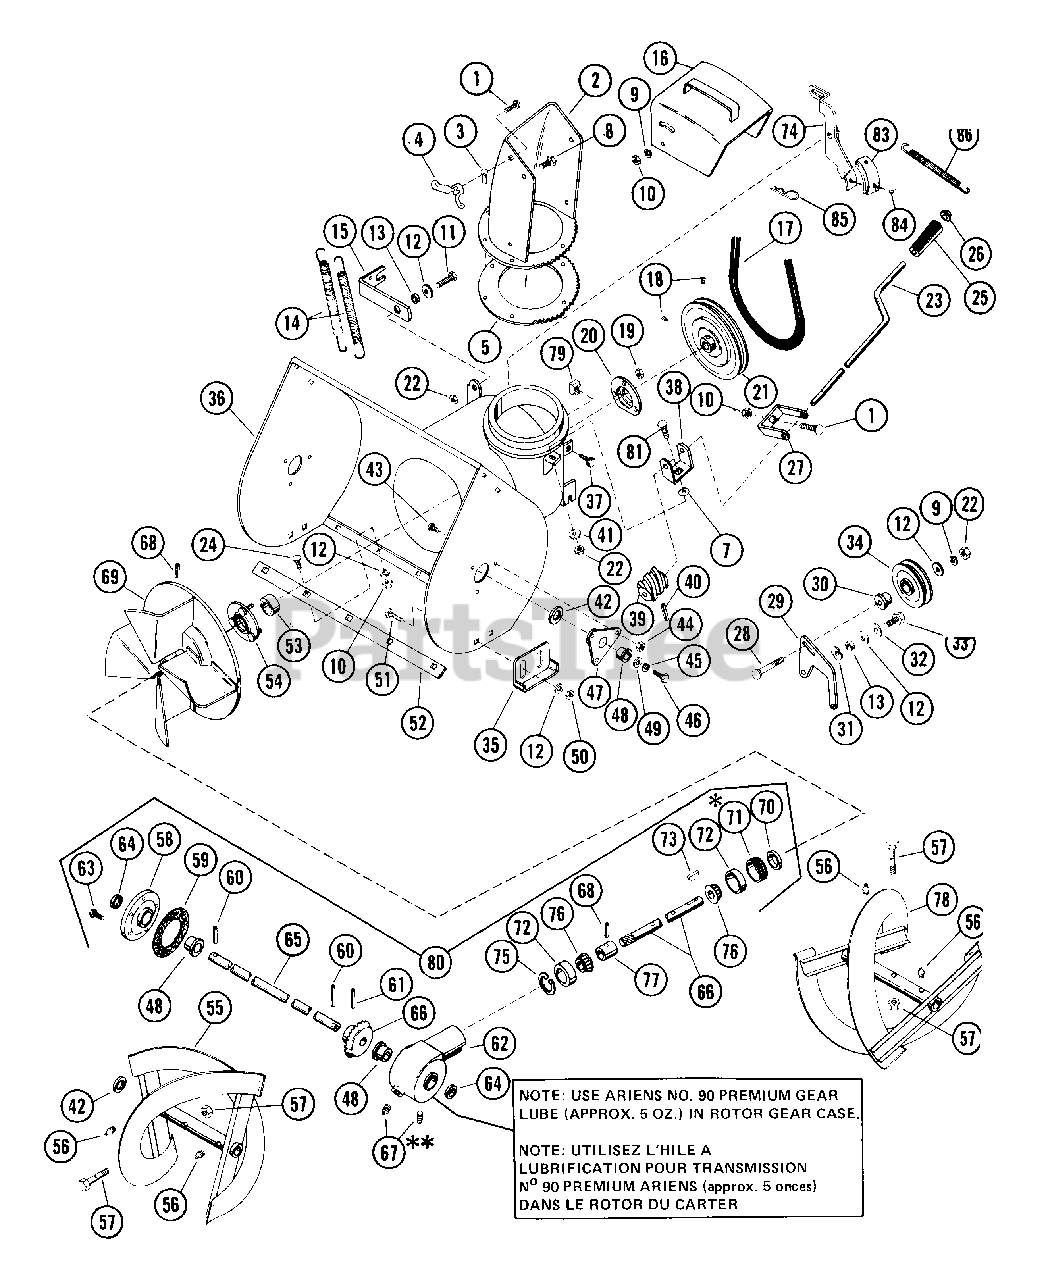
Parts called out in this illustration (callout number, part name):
1	BLT-RDHDSQSHNK .31-18X.50 YZ
2	CHUTE - DISCHARGE
3	SCR-TAP 8-32X.38 SL HWH PL 23
4	WING NUT, .312-18
5	GEAR - LOWER COLLAR
7	WSHR-LK-EXT .313X.030 PL
8	BLT-HEX .31-18X.50 PL GR2
9	WSHR-LK .312X.097 PL HVY
10	NUT-LK .312-18 GR A PL
11	BLT-HEX .31-18X.75 PL GR2
12	WSHR-FL-STL .38X.875X.083 PL
13	SPACER BUSHING .5 X .32 X .21
14	SG-TENS .125X.437X5.5 WLD 20
15	CLUTCH LEVER
16	DEFLECTOR SERVICE ASSEMBLY
17	V-BELT, 4L-WRAPPED
18	SCR-SET .32-18X.38 SKHCUPNL OH
19	NUT-LK-CTR .250-20 PL
20	BEARING FLANGE
21	PLY-V 8.00 X .75 W/KEY SALEM
22	NUT-HEX .312-18
23	CHUTE CONTROL CRANK
24	BLT-RDHDSQNK .312-18X.62 PL
26	CAP, 3/8 ROD YWZC
27	BRACKET ASSEMBLY
28	BLT-RDHDSQNK .31-18X1.38SHT PL
29	IDLER ARM
30	SPCR, BRG .315X.50X.688X.281
31	WAVE WASHER .531X.781X.125FH
32	WSHR-LK-INT .313X.030 PL
33	BLT-HEX .31-18X.63 PL GR 2
34	IDLER
35	RUNNER
36	BLOWER HOUSING ASSEMBLY
37	BLT-SCRHFWH .38-16X.75 PL
38	WORM CLEVIS
39	WORM GEAR
40	PIN-ROLL .125X.75
41	WSHR-LK .313X.062
42	WSHR-FL-STL 1.010X1.505X.062PL
43	SCR-SLTR-SERNK .25-20X.62 PL
44	NUT-LK-FLG .250-20 PL
45	WSHR-LK .500X.151 HVY PL
46	BLT-HEX .50-13X1.00 PL GR2
47	BEARING SUPPORT
48	BSHG-FLG 1.000X1.12X.62X1.50BR
49	WSHR-FL-STL .511X1.441X.125 PL
50	NUT-LK-CTR .375-16 GR A PL
51	BLT-RDHDSQNK .38-16X.75 SHT PL
52	SCRAPER BLADE
53	BRG-BALL .750X1.750X.50
54	BEARING FLANGE
55	RAKE, RIGHT-20"(1ID X 13.88OD)
55	RAKE, RIGHT-24"(1ID X 13.75OD)
56	SPIN DRIVE ZERK FITTING
57	SHEAR BOLT SERVICE ASSEMBLY
58	GEAR CASE FLANGE
60	PIN-ROLL .188X1.50
61	PIN-ROLL .313X1.38
62	CASE, GEAR - C.I.
63	BLT-SERHFWH .25-20X.75 PL
64	SEAL 1.000X1.312X.150
65	FRONT GEAR SHAFT
66	SHAFT & GEAR SERVICE ASSEMBLY
67	PIPE PLUG
68	PIN-ROLL .250X1.25
70	SEAL .750X1.499X.225
71	ADJUSTMENT PLUG
72	BRG-CUP 1.781X.475
73	KEY-WDRF .188X.75X.313 SAE 9
74	BRAKE ASSEMBLY
75	RG-RTNG INT 1.781 HSG X.062
76	BRG-CONE .750X.61
77	BEARING SPACER
78	RAKE, LEFT-20"(1ID X 13.88 OD)
78	RAKE, LEFT-24"(1ID X 13.75 OD)
79	NUT-RETNR .38-16 TINRMAN
80	GEAR CASE - C.I.
80	GEAR CASE - 24" - CAST IRON
81	BLT-RDHDSQNK .31-18X.75 GR5 PL
83	BRAKE LINING
84	RVT-TBLR .187X.375 OH ST PL
85	PIN-HAIR INT .08X.18X1.18
86	SG-TENS .062X.56X8.0 WLD 11
